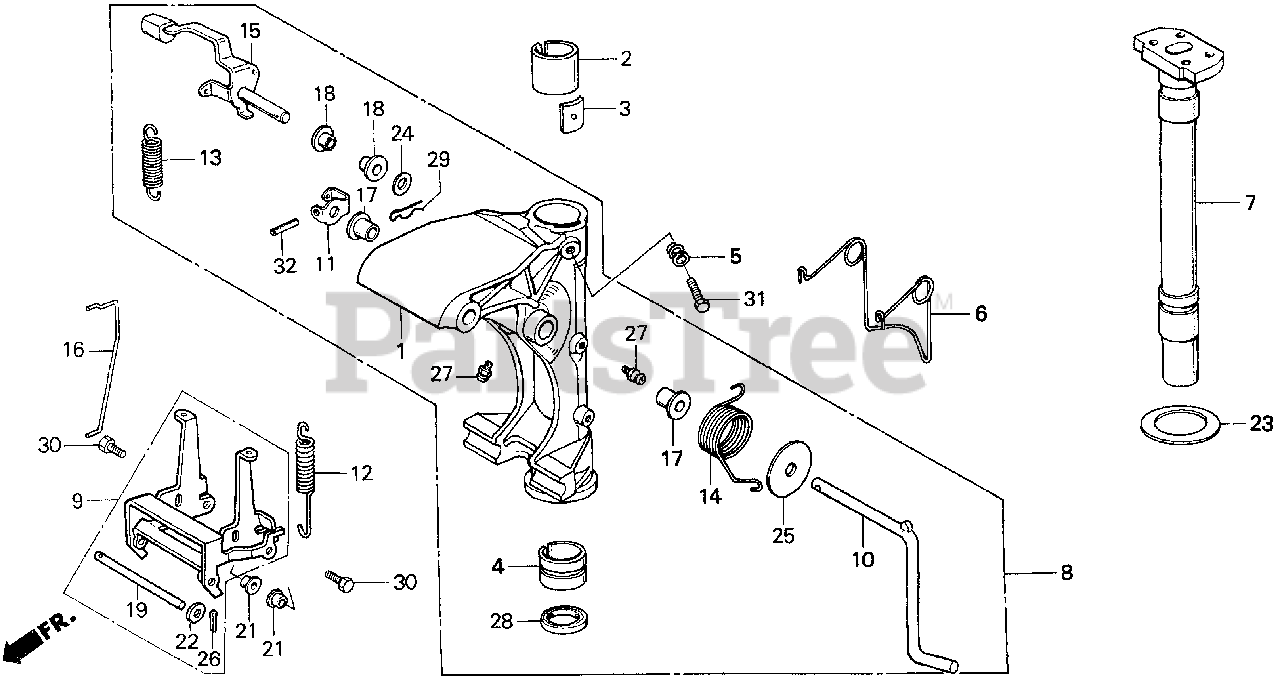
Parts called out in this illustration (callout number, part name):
1	CASE, SWIVEL *B107* (SENIOR BLUE) (NOT AVAILABLE)
2	LINER, SWIVEL CASE
3	BLOCK, FRICTION
4	BUSH, SWIVEL SHAFT
5	SPRING, FRICTION ADJUSTING
6	SPRING, HOOK RETURN
7	SHAFT, SWIVEL *B107* (SENIOR BLUE) (NOT AVAILABLE)
8	CASE, SWIVEL *B107* (SENIOR BLUE) (NOT AVAILABLE)
9	LOCK, REVERSE
10	LINK, TILT (NOT AVAILABLE)
11	BRACKET, TILT LEVER (NOT AVAILABLE)
12	SPRING, REVERSE LOCK
13	SPRING, TILT LEVER (NOT AVAILABLE)
14	SPRING, TILT LINK (NOT AVAILABLE)
15	LEVER, TILT (NOT AVAILABLE)
16	ROD, RELEASE SWIVEL CASE
17	BUSH, TILT LEVER (NOT AVAILABLE)
18	BUSH B, TILT LEVER (NOT AVAILABLE)
19	ROD, REVERSE LOCK
21	COLLAR (6MM) (NOT AVAILABLE)
22	WASHER, PLAIN (5MM)
23	WASHER, THRUST
24	WASHER, PLAIN (10MM)
25	WASHER, PLAIN (10MM)
26	PIN, COTTER (1.6MM)
27	FITTING, GREASE
28	OIL SEAL (32X37X7)
29	PIN, LOCK (10MM)
30	BOLT, HEX. (6X16)
31	BOLT, HEX. (8X20) (NOT AVAILABLE)
32	PIN, SPRING (4X25)
